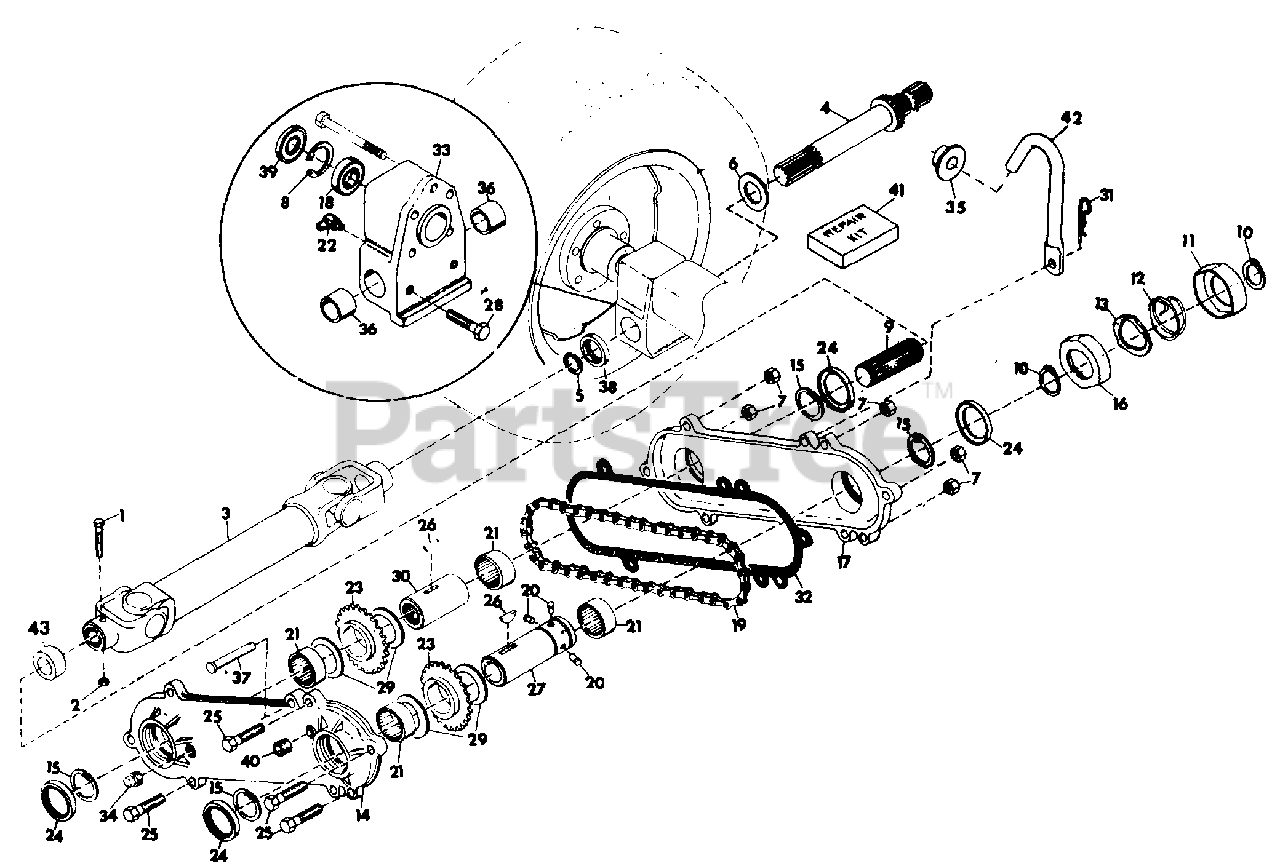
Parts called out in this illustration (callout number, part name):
1	BOLT, HEX 1/4-20 X 2
2	NUT, LOCK 1/4-20
3	UNIVERSAL DRIVE SHAFT
4	SHAFT
5	RING, RETAINING
6	THRUST RACE
7	NUT, LOCK 3/8-16
8	RING, RETAINING
9	SHAFT
10	RING, RETAINING
11	RETAINER, OUTER
12	SPRING
13	CAM
14	HOUSING, FRONT
15	RING, RETAINING
16	RETAINER, INNER
17	HOUSING, REAR
18	BEARING, BALL
19	CHAIN
20	PIN
21	BEARING, NEEDLE
22	GREASE FITTING
23	SPROCKET
24	SEAL, OIL
25	BOLT, HEX 3/8-16 X 2
26	KEY, WOODRUFF 3/16 X 5/8
27	SHAFT
28	BOLT, HEX 1/2-13 X 1
29	THRUST RACE
30	SHAFT
31	HAIR PIN COTTER
32	GASKET
33	AXLE BEARING RETAINER & BUSHINGS
34	PLUG, PIPE 1/2 IN.
35	BUSHING, NYLON
36	BEARING
37	PIN, CLEVIS 3/8 X 1.875
38	THRUST RACE
39	SEAL, OIL
40	PLUG, VENTED
41	REPAIR KIT FOR UNIVERSAL SHAFT
42	BRACKET, REAR PTO
43	SPACER, 1.060X1.375X.450
